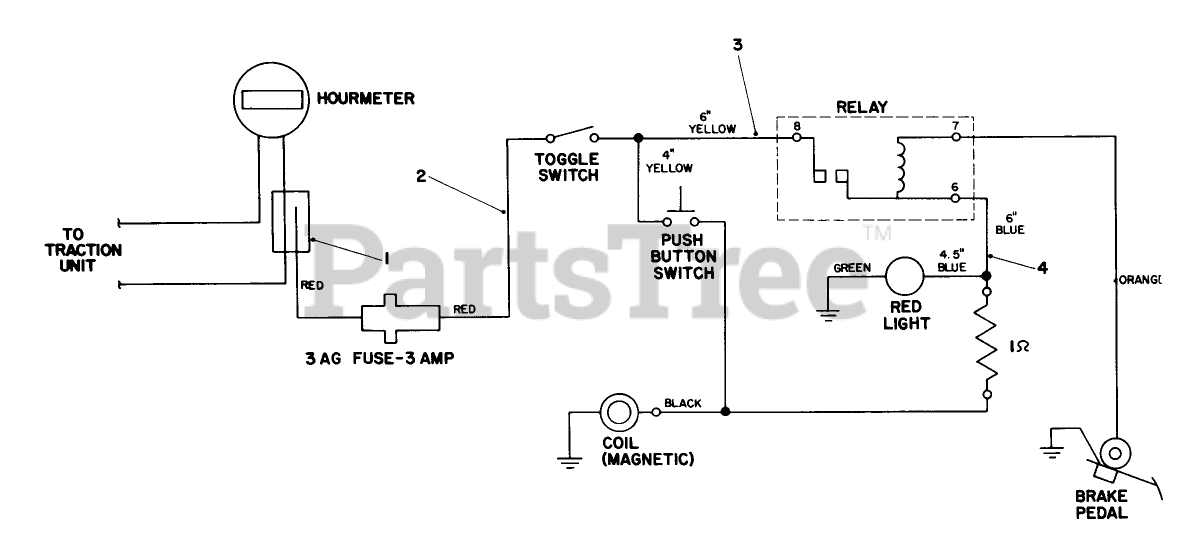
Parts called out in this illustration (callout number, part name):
1	TAP CONNECTOR
2	Wire Harness
3	WIRE ASM
4	WIRE ASM
